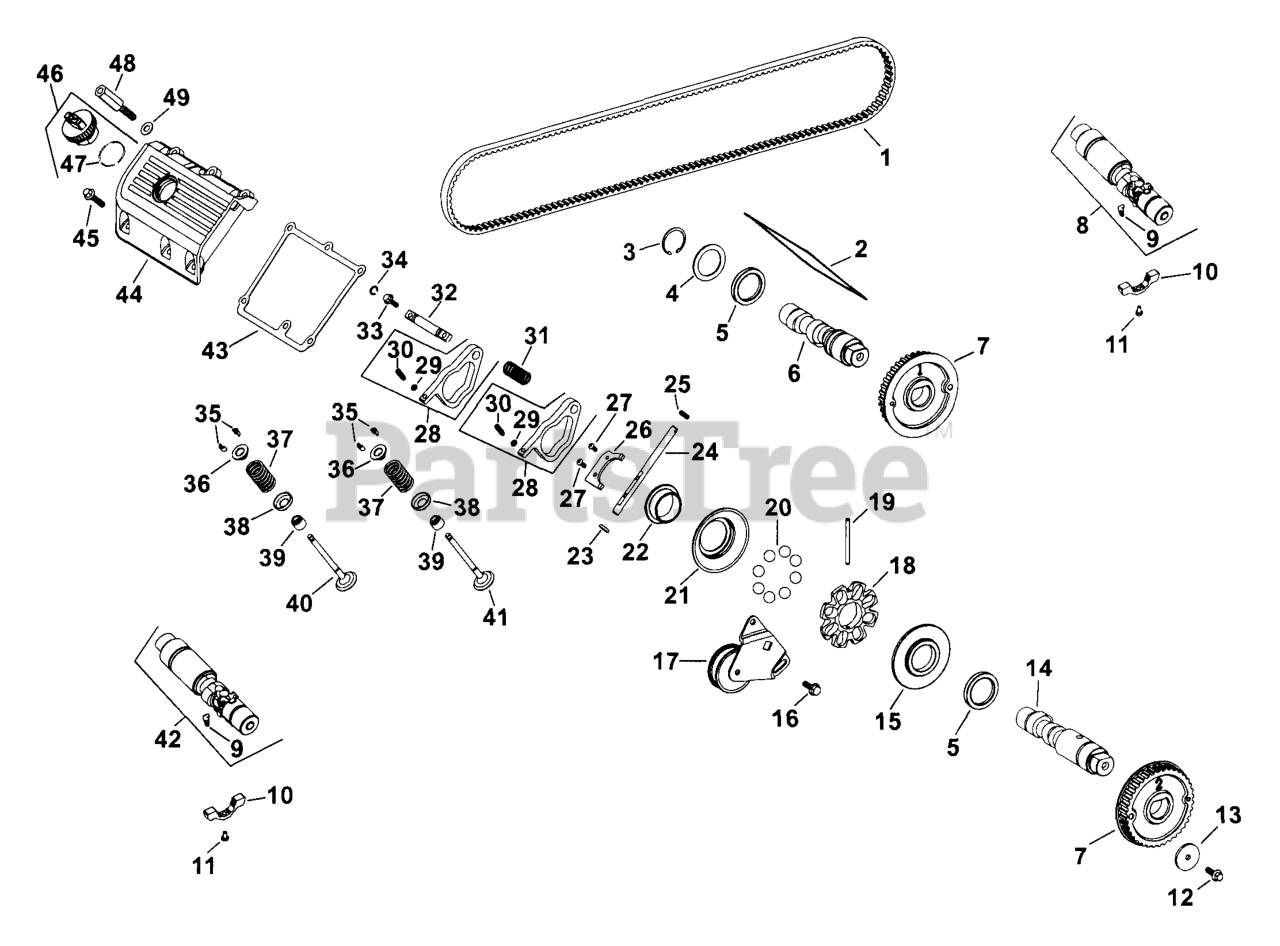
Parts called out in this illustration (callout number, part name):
1	BELT, TIMING
2	GASKET, VALVE COVER NO. 1
3	RING, SNAP - DISCONTINUED
4	WASHER, THRUST (#DSC)
5	SEAL, OIL - DISCONTINUED - USE (CLARK TP-32-44-6 P)
6	CAMSHAFT, NO. 1 CYLINDER
7	SPROCKET, CAMSHAFT - DISCONTINUED
12	SCREW, FLG M6X1.0X16
13	WASHER, FLAT - DISCONTINUED
14	CAMSHAFT, NO. 2 CYLINDER
15	PLATE, BACKING GOVERNOR - (#DSC)
16	SCREW,FLG THD FRM M6X1.0X20-(#25086396S)
17	PULLEY, IDLER
18	BODY, GOVERNOR
19	PIN, COILED SPRING
20	BALL, GOVERNOR
21	COVER, GOVERNOR - DISCONTINUED
22	BUSHING, GOVERNOR - DISCONTINUED
23	SPACER, GOVERNOR
24	SHAFT, GOVERNOR CROSS
25	SEAL, GOVERNOR-CROSS SHAFT
26	YOKE, GOVERNOR
27	Screw, hex. socket button head M4x0.7x10
28	KIT, ROCKER ARM
29	NUT, HEX JAM
30	SCREW, SLOTTED SET
31	SPRING, SHAFT - DISCONTINUED
32	SHAFT, ROCKER ARM - (#DSC)
33	SCREW,FLG THD FRM M5X0.8X16-(#25086398S)
34	RING, RETAINING (#DSC)
35	LOCK, RETAINER
36	CAP, VALVE SPRING (#DSC)
37	SPRING, VALVE - (#DSC)
38	RETAINER, VALVE SPRING - (#DSC)
39	SEAL, VALVE STEM-USE 20 032 10-S
40	VALVE, EXHAUST - DISCONTINUED
40	VALVE, EXHAUST .250 O/S - DISCONTINUED
41	VALVE, INTAKE-(#DSC)
41	VALVE, INTAKE .250 O/S-DISCONTINUED
43	GASKET, VALVE COVER NO. 2
44	COVER, VALVE NO. 2
45	SCREW,FLG M6X1.0X25 (#25086294S)
46	CAP ASSY, OIL FILL (YELLOW)
47	O-RING-USE 24 153 32-S
48	SPACER, THREADED - DISCONTINUED
49	WASHER, FLAT 1/4" (O.D. 1/2")
